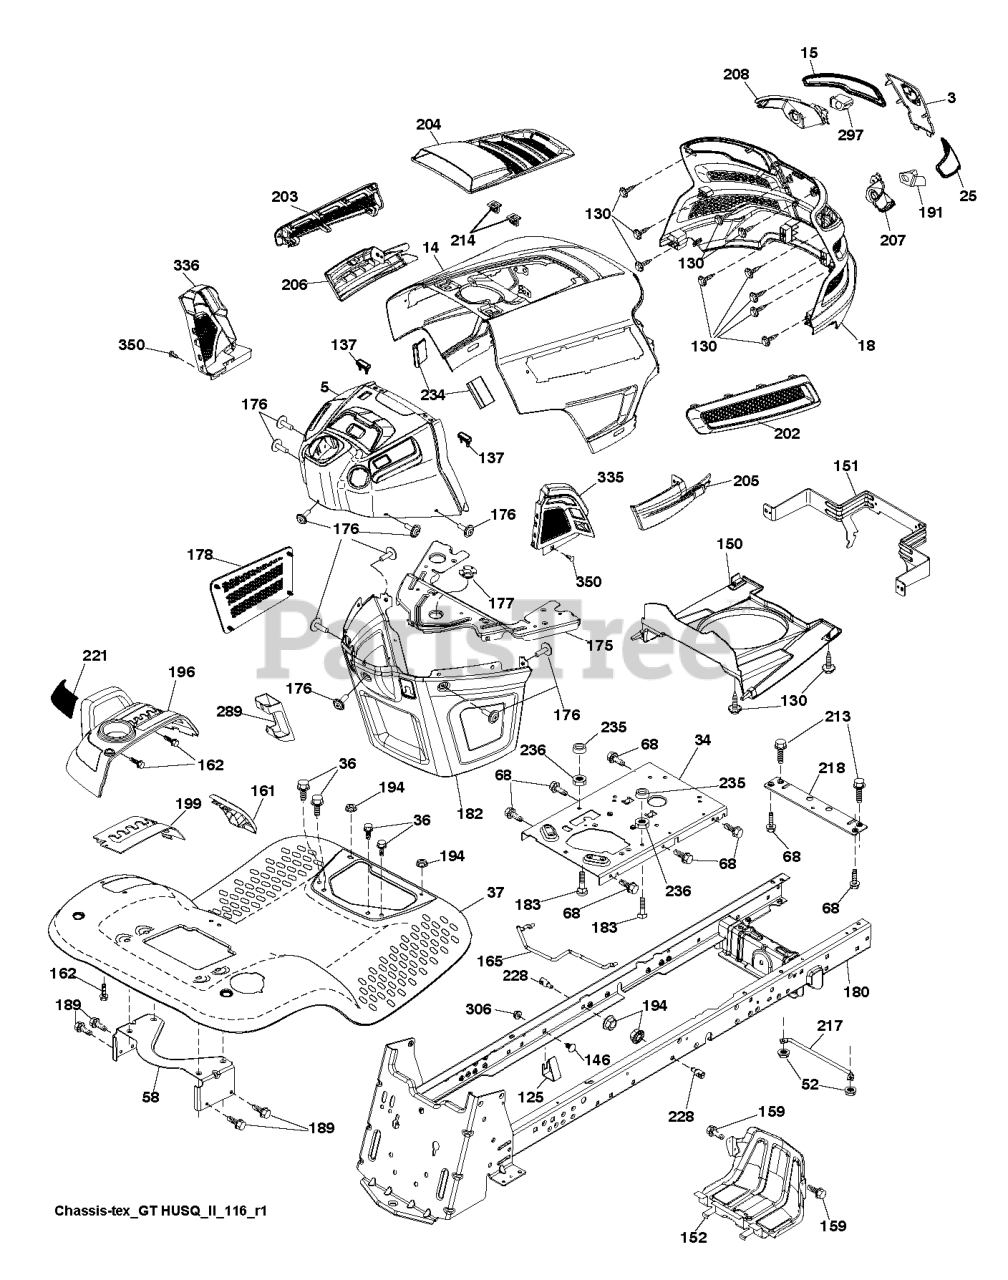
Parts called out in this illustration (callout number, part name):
3	APPLIQUE.SUBASM.GT.HUSQ.II
5	DASH.UPR.ASSY.GT2.SRVMNDER.PTO
14	HOOD.ASM.HUSQVARNA.GT.TEX.ORAN
15	LENS.HEADLIGHT.LH.GTII.2011
18	GRILLE.SUBASM.GT.HUSQ.II
25	LENS.HEADLIGHT.RH.GTII.2011
34	PLATE PLATE ENGINE
36	SCREW 5/16"
37	FENDER.PNT.TX.GT.CH/FW/DL.HUSQ
52	LOCKNUT
58	BRKT.SUPPORT.FNDR/TANK
68	SCREW LT
130	SCREW.#10 X 0.750.BOS
137	BUMPER DASH
150	AIR.DUCT.GTV.BLACK
151	BRACKET.PIVOT.HOOD.GT.HUSQ.II
152	SHIELD.BROWNING.PNT.GT.V2
159	SCREW, 3/8-16X3/4
161	CONSOLE.WINDOW.FUEL.HUSQ.GT
162	SCREW.HI-LO.CONSOLE
165	SUPPORT.TANK.REAR.W/TEX
175	PLATE.CROSSMEMBER.HUSQ
176	SCREW.#10-24X5/8.RN.QU
177	BUSHING, STEERING
178	CARGO.ASM.NET.TXGT.W/C
180	CHASSIS.GT.SLOPED.DRAWBAR.
182	DASH.LOWER.COMMON.12V.ADAPTOR
183	BOLT.5/16-18X1-1/4 FULL THD
189	SCREW, 3/8-16X3/4
191	INSERT.REFLECTIVE.RH.HUSQ.GTII
194	NUT LOCK HEX FLANGE 5/16-18
196	SUBASM.CONSOLE.HUSQ.GT.DECKLFT
199	PLATE.DECK.LIFT.HUSQVARNA.GT
202	VENT.SIDE.RH.GT.HUSQ.II.
203	VENT.SIDE.LH.GT.HUSQ.II.498
204	VENT.TOP.HUSQ.GT2
205	SIDE.TRIM.RH.GT.HUSQ.II
206	SIDE.TRIM.LH.GT.HUSQ.II.GRAY
207	BEZEL LIGHT.RH.GT.II.MYLAR
208	BEZEL LIGHT.LH.GT.II.MYLAR
213	BOLT
214	CLIP.RETAINER.TINNER.
217	ROD.PIVOT.HOOD
218	X-PIECE.HOOD.STOP.NON/
221	REFLECTOR.LH.TEX GT HU
228	STUD.FASTNER.W/ANTI-ROTATE
234	BUMPER.HOOD.TEX.HUSQVARNA
235	SPACER FENDER
236	NUT.CENTERLOCK.5/16-
289	PLUG.N/CRUISE.COMMON.YT/GT.BLK
297	INSERT.REFLECTIVE.LH.HUSQ.GTII
335	COVER.LOWER.DASH.RH.BLACK
336	COVER-LH.LOWER.DASH.GT2.BLACK
350	CLIP.X-MAS.TREE
